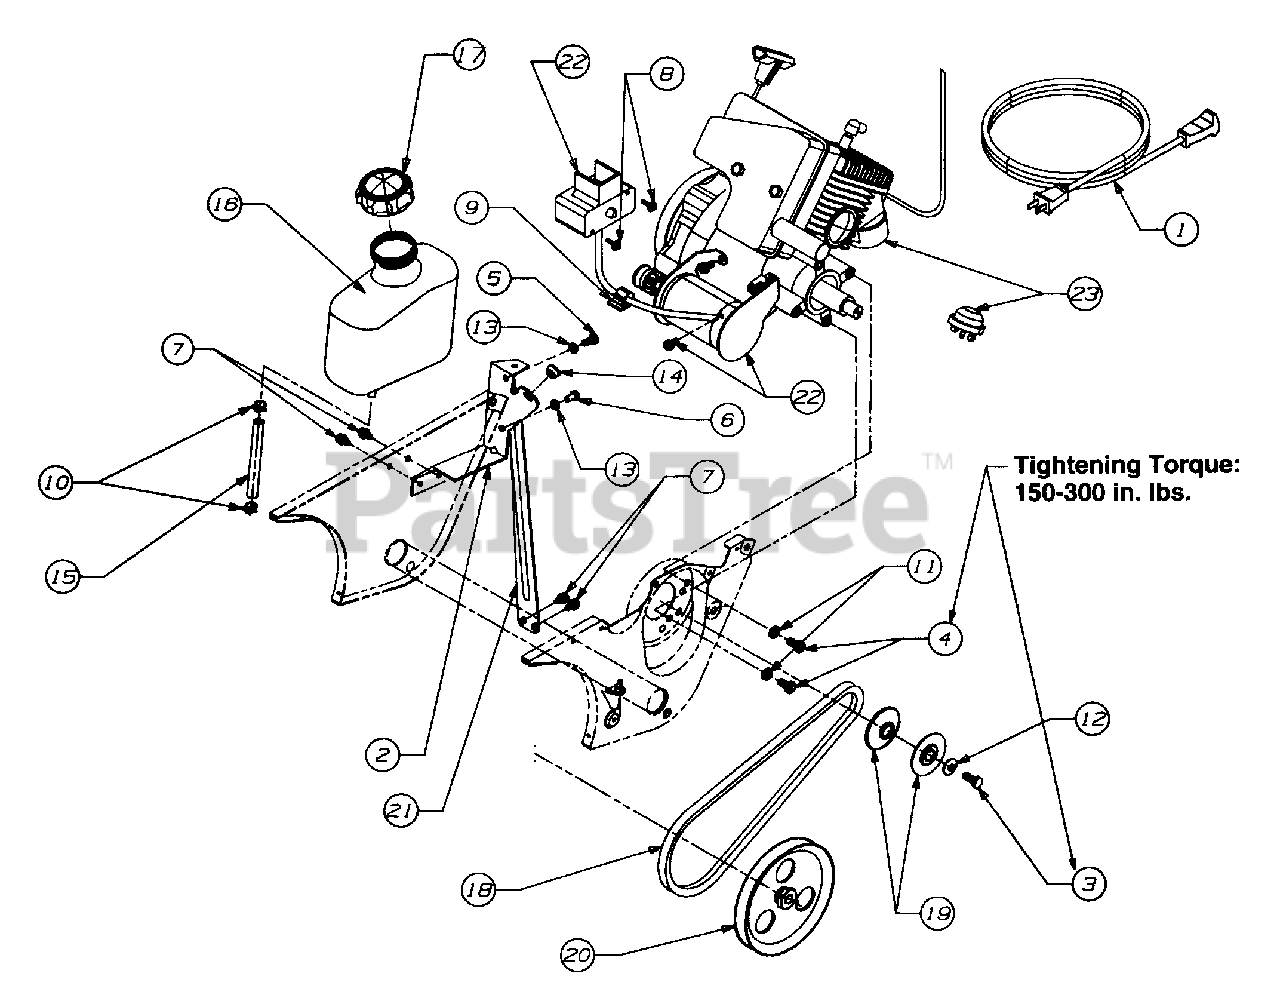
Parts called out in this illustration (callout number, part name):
1	Cord-Ext. 110V 2-Prong
2	Gas Tank Support Bracket
3	Screw-Hex
4	Screw-Hex
5	Screw-Hex
6	Screw-Hex
7	Screw-Hex
8	Screw-Hex
9	Clamp-Mounting
10	Clamp-Hose
11	Washer-Lock
12	Washer-Bell
13	Washer-Lock
14	Bushing
15	Hose-Fuel Line, 16"
16	Tank-2 Quart
17	Fuel Cap
18	V-Belt
19	V-Pulley Half
20	Pulley
23	Obtain From Engine Mfgr.
